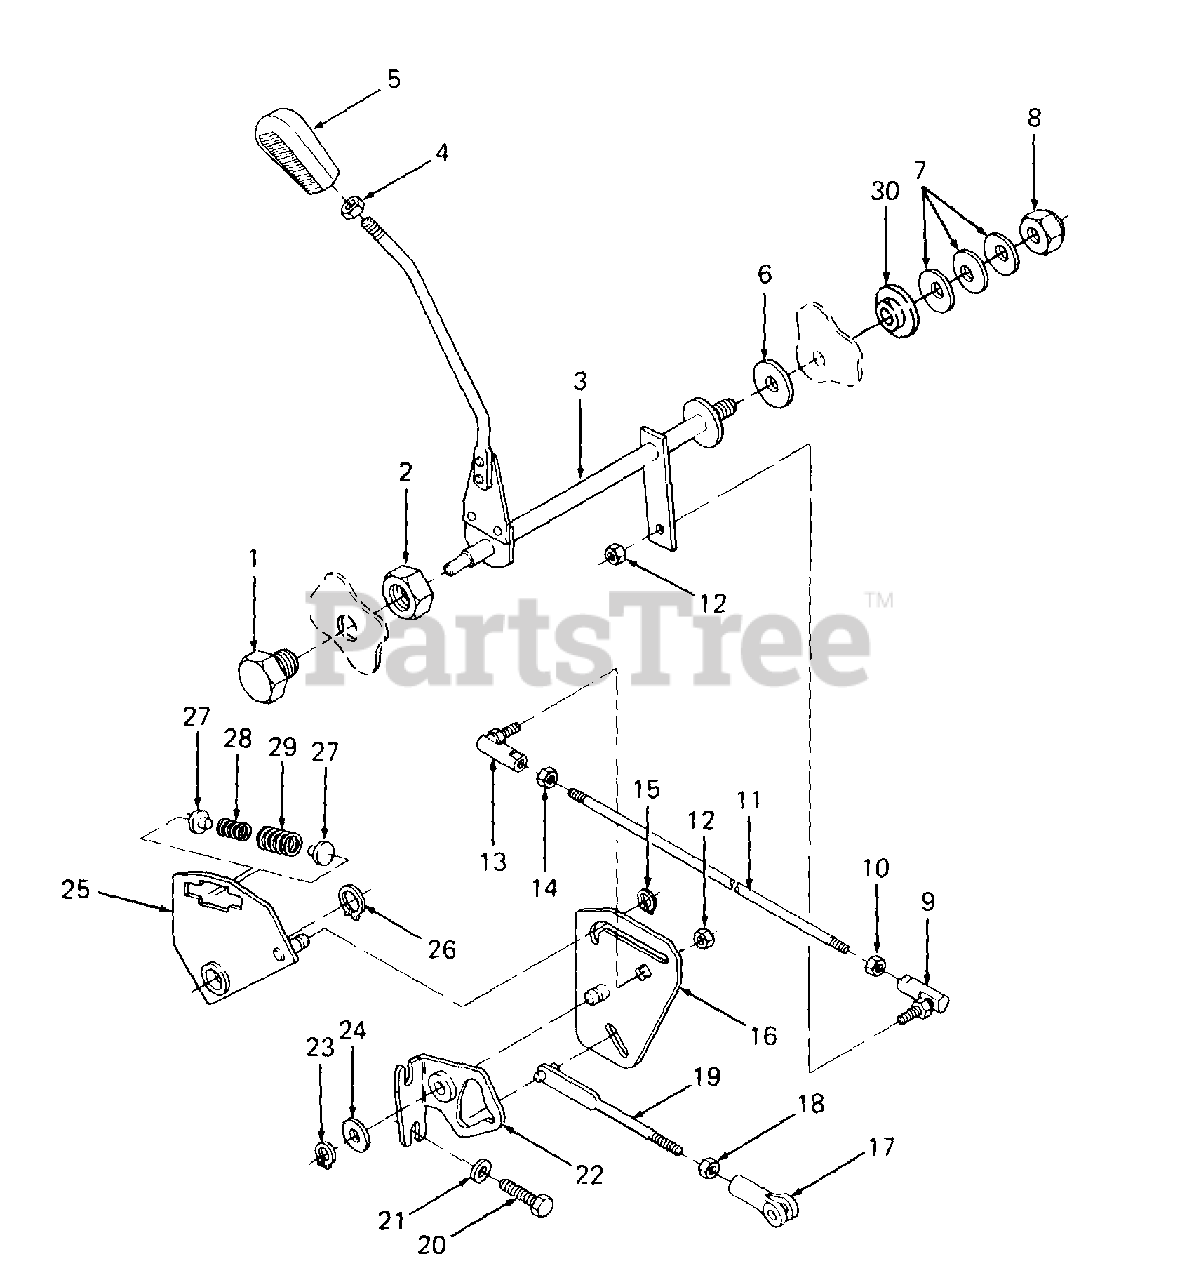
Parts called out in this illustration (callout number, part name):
1	Screw, Rockshaft Bearing, 3/4-16 x .75 Lg
2	Nut, Hex Jam, 3/4-16 GR5
3	Shaft Assy, Cross
4	Nut, Hex Jam, 3/8-16 GR5
5	Knob, Speed Control
6	Disc, Friction
7	Washer, Bell
8	Nut, Hex Top Lock, 1/2-20
9	Ball Joint, 5/16-24
10	Nut, Hex Jam, 5/16-24
11	Rod, Connecting
12	Nut, Hex Patch Lock, 5/16-24
13	Ball Joint, 5/16-24 LH Trd
14	Nut, Hex Jam, 5/16-24 LH Trd
15	Ring, Retaining, .375
16	Cam, Control
17	Clevis Adjustment
18	Nut, Hex Jam, 3/8-24 GR5
19	Rod, Control
20	Screw, Hex Cap, 3/8-16 x 1.5 Lg GR5
21	Washer, Flat, .385 x .87 x .06 Thk HDN
22	Bracket, Cam Pivot
23	Ring, Snap, .500
24	Washer, Flat, .510 x 1.0 x .060 Thk
25	Plate Assy, Damper Spring
26	Ring, Snap, .625
27	Pin, Spring Guide
28	Spring, Compression
29	Spring, Compression
30	Spacer, Shouldered
